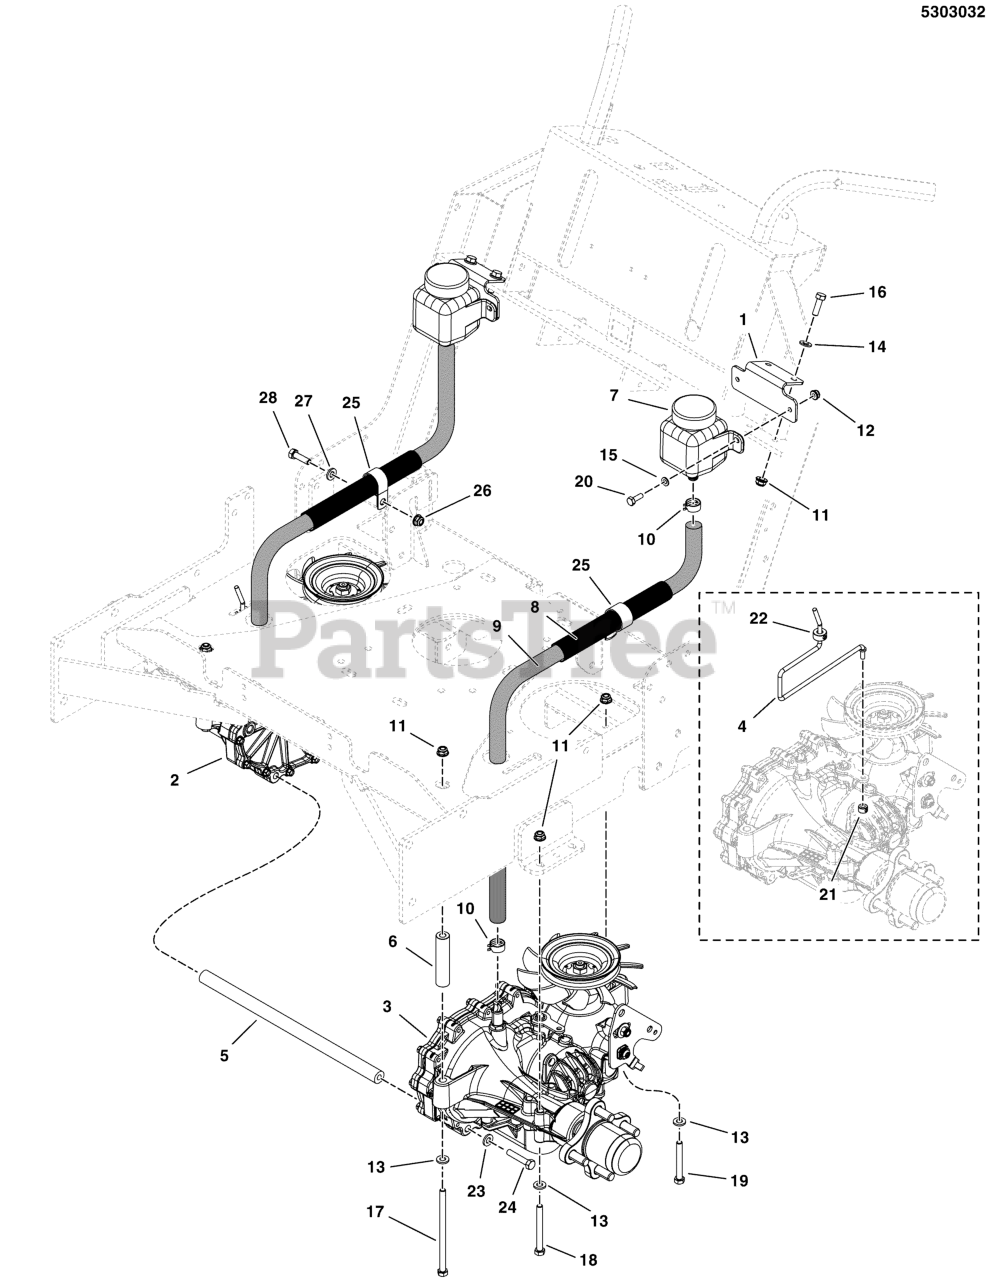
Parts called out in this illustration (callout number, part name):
1	PLATE, HYDRO BOTTLE, MOUNT - RED
2	TRANSAXLE, ZT3100, RH(ZJ-KMFE-3C5C-1RLX)
3	TRANSAXLE, ZT3100, LH(ZJ-GMFE-3B5B-1RLX)
4	ROD, HYDRO RELEASE, SW30
5	ROD, HYDRO LINK, 3/8, CZ
6	SPACER, .34 X .75 X 3.27, CZ
7	HYDRO RES. #71328, 350 ml
8	WIRE LOOM, 3/4 ID X 24 IN
9	HOSE, 1/2" PUSH-ON, 24.00"
10	CLAMP, HOSE, .75 FREE DIA.
11	NUT, 5/16-18 HEX NYLOCK FLANGE
12	NUT, 1/4-20 HEX NYLOCK FLANGE
13	WASHER, 5/16 GD.9 FLAT
14	WASHER, 5/16" SAE
15	WASHER, 1/4 SAE
16	BOLT, 5/16-18 X 1 GD5 YZ
17	BOLT, 5/16-18 X 6, GD 5, YZ
18	BOLT, 5/16-18 X 2-3/4, GD 5, YZ
19	BOLT, 5/16-18 X 2-1/4 GD5 YZ
20	BOLT, 1/4-20 X 3/4 GD5 YZ
21	COLLAR, 1/4 SET
22	COLLAR, 5/16 SET
23	WASHER, 3/8 GD.9 FLAT
24	BOLT, HEX, 3/8-16 X 2-1/4, GD8, PLAIN
25	CLAMP, HOSE, 1.000 DIA.
26	NUT, 3/8-16 HEX NYLOCK FLANGE
27	WASHER, 5/16" SAE
28	BOLT, 3/8-16 X 1" GD5 CZ
